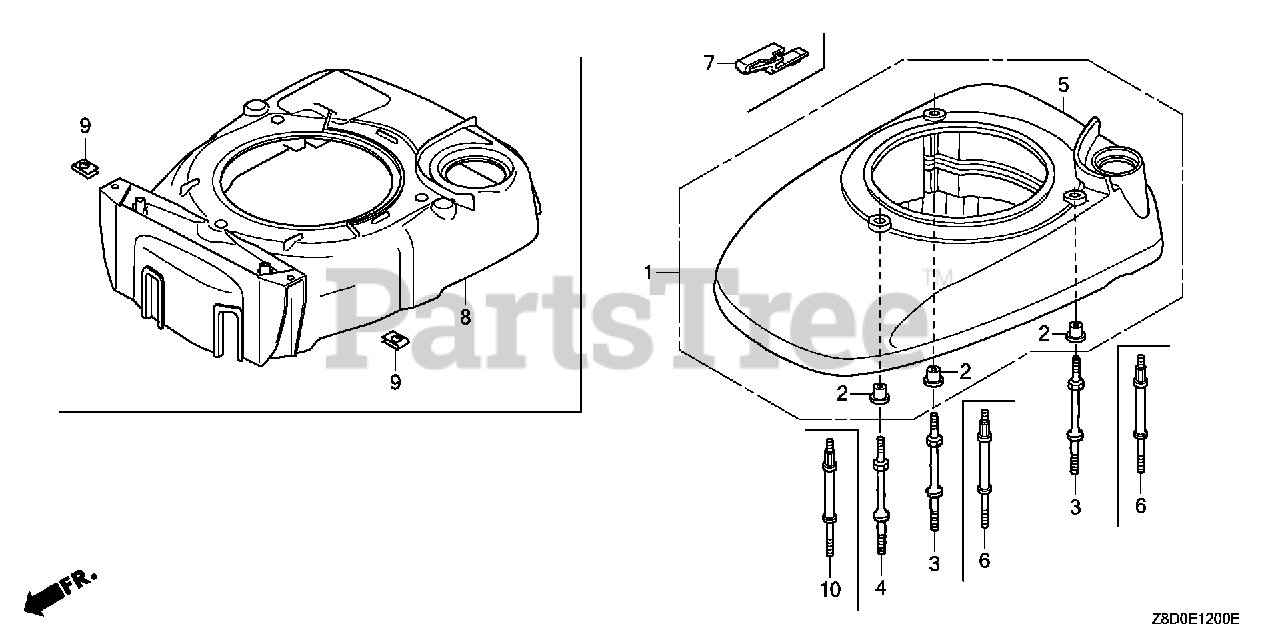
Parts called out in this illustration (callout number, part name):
6	BOLT, STUD (FAN COVER)
7	CLIP, TANK MOUNTING *NH1* (BLACK)
8	COVER, FAN *NH1* (BLACK)
9	NUT, CENTER PANEL
10	BOLT, STUD (FAN COVER)
